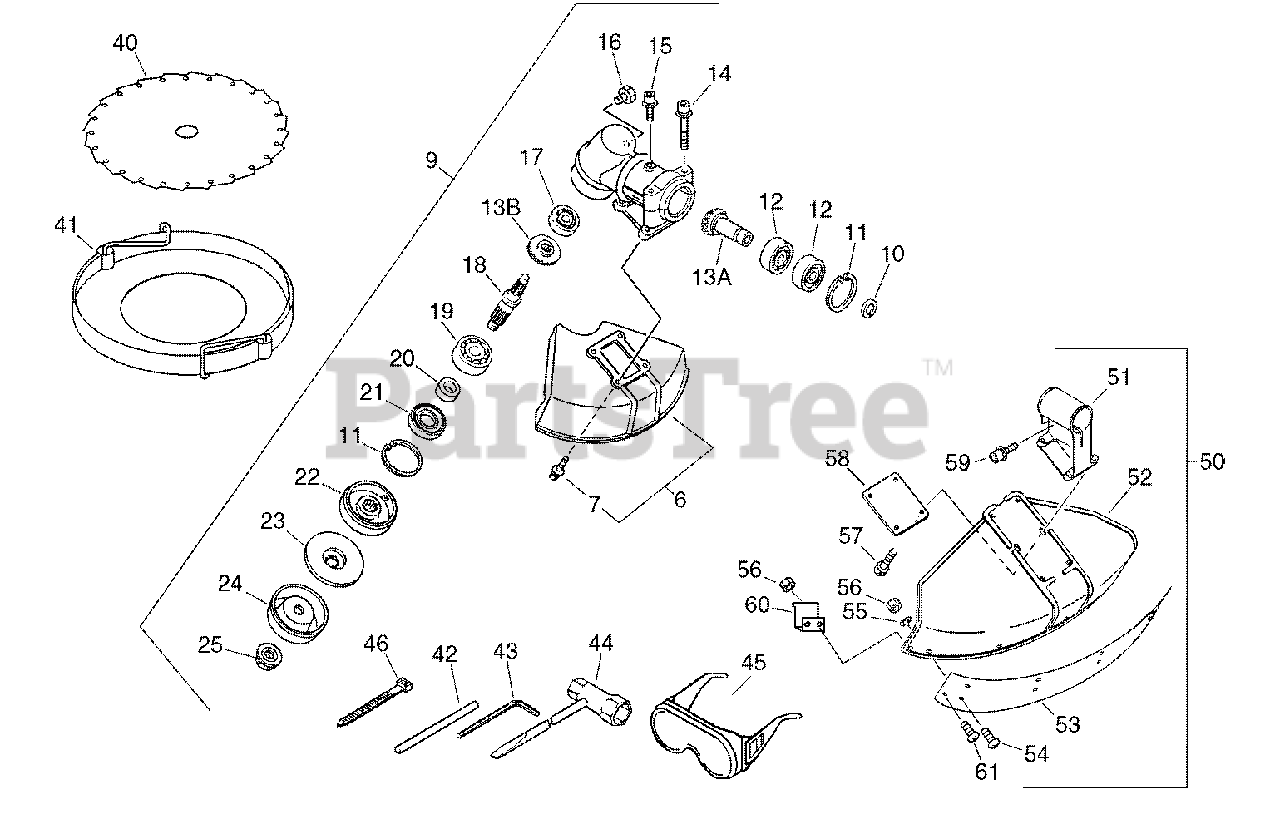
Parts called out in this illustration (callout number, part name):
6	DEBRIS SHIELD KIT
7	SCREW - 5X20
9	GEAR CASE ASSY
10	RING, RETAINING - 15
11	RING, RETAINING - 35
12	BEARING, BALL - 6202
13	GEAR SET
14	SCREW - 5X35
15	SCREW - 5X14
16	BOLT - 8X8
17	BEARING, BALL - 6001
18	GEAR - SHAFT
19	BEARING, BALL - 6202Z
20	SPACER, OILSEAL
21	SEAL, OIL
22	ADAPTOR, BLADE - UPPER
23	ADAPTOR, BLADE - LOWER
24	PLATE, CUP
40	SAW, EIA200-20
41	BLADE COVER KIT
42	LOCKING TOOL
43	HEX KEY - 4mm
44	T-WRENCH - 17X19mm
45	GOGGLES
46	TIE, CABLE - SMALL
50	DEBRIS SHIELD KIT
51	BRACKET, SHIELD
52	SHIELD, DEBRIS
53	GUARD, SHIELD
54	SCREW - 5X14
55	WASHER - 5
56	NUT - 5
57	SCREW - 5X18
58	BRACKET, SHIELD
59	SCREW - 5X25
60	KNIFE, TRIMMER LINE
61	SCREW - 5X12
